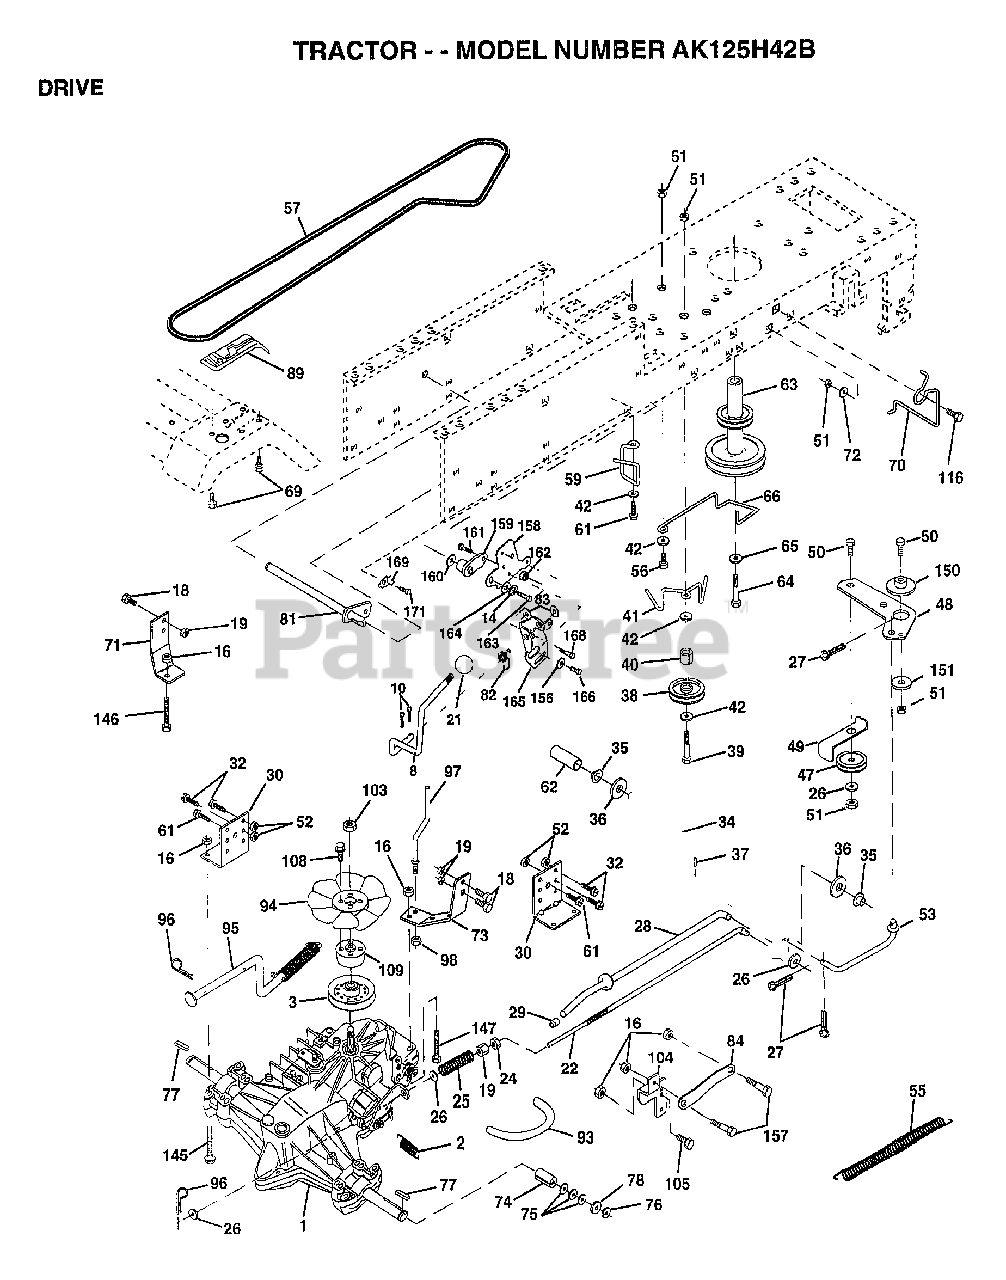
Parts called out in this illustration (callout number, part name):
1	TRANSAXLE HYD 0319-0500
2	SPRING RET BRAKE
3	PULLEY.4.20.HYDRO
8	ROD.SHIFT.FENDER.ADJ.LT.CRD
10	PIN COTTER 1/8
14	LOCKWASHER
16	NUT
18	BOLT
19	NUT
21	KNOB T (1/2-HOLE)
22	ROD.BRAKE.HYDRO.
24	NUT
25	SPRING ROD LT
26	WASHER
27	COTTER PIN
28	ROD.BRAKE.PARK.LT
29	PLUNGER CAP T
30	TRANSAXLE MTG BKT
32	BOLT
34	SHAFT ASM-PEDAL F
35	NYLON BEARING
36	WASHER LT
38	FLAT IDLER PULLEY
39	BOLT
40	SPACER T
41	"KEEPER,BELT.IDLER FLAT"
42	WASHER
48	BELLCRANK.CLUTCH
49	RETAIN BELT
53	"LINK, CLUTCH T"
55	"SPRING, RETURN LT"
57	BELT-V.HYDR.84.61
59	KEEPER BELT CNTSP
61	SCREW
62	PEDAL COVER T
63	PULLEY.ENGINE
64	BOLT
65	LOCKWASHER
66	KEEPER-BELT
69	SCREW HEXWSH H-L
70	KEEPER BELT ENG
71	STRAP.TORQ.LH.HYD
72	WASHER
73	STRAP.TORQ.RH.HYD
74	SPACER SPLIT
75	WASHER
76	E-RING LT
77	SQUARE KEY
78	WASHER
81	SHAFT ASM.CROSS
82	"SPRING,TORSION"
83	WASHER
84	LINK.TRANSAXLE.HYDR
89	CONSOLE.SHIFT.LT
93	"LINE FUEL HYD 4"""
94	"FAN 7"" HYDRO"
96	RETAINER M
97	KEEPER.BELT.RH.HY
98	NUT
104	ARM.CONTROL.PUMP
105	SCREW CAP 5/16-18
108	SCREW.HXHD.10-20
109	ADAPTOR.FAN.HYDRO
116	BOLT RDHD 3/8-16
145	BOLT.HEX.FLGHD
146	BOLT.HEX.FLGHD.
147	BOLT.HEX.FLGHD
150	BUSHING.BELLCRANK.GRD.DR
151	WASHER
156	WASHER.SRRTD.5/16
157	"BOLT,SHOULDER"
158	BRKT.SHIFT.MOUNT
159	HUB.SHIFT
160	WASHER
161	BOLT T
164	WASHER.5/8X.281X10GA
165	BRKT.PIVOT.LEVER
166	SCREW.5/16-18X5/8
168	BOLT.SHOULDER.5/16-18X.561
169	PLATE.FASTENING
171	SCREW LT
